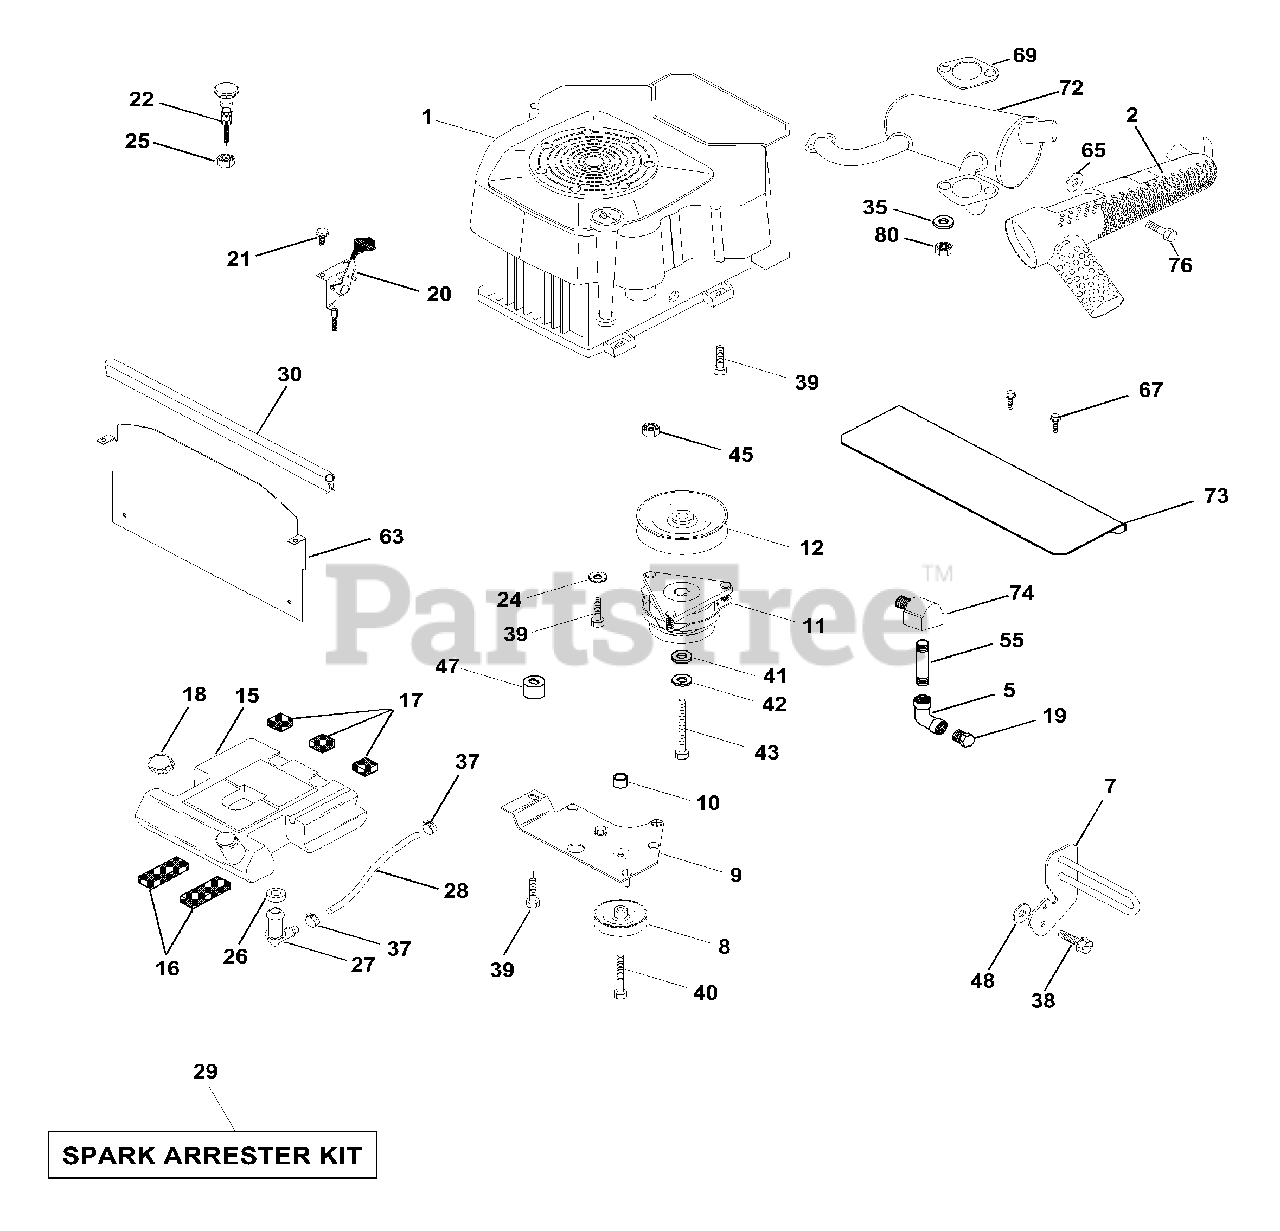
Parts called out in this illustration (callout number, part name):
2	Muffler Side
5	Elbow STD 90 Degree 3/8-18 NPT
7	Muffler Assembly Guard
8	Pulley V-Idler
9	Keeper Asm Belt Engine VGT 96
11	Clutch Electric
12	Pulley Engine VGT Elect Clutch
15	Tank Fuel Rear
16	Pad Spacer
17	Pad Spacer
18	Cap Asm Fuel W/Sym Vented
19	Plug Oil Drain
20	Control Throttle
21	Screw Hex Thd Cut 1/4-20 X 5/8
22	Control Choke
24	Washer Ext Tooth 3/8
25	Nut Keps 3/8 - 24 UNF
26	Bushing
27	Stem Tank Fuel
28	Fuel Line
29	Spark Arrester Kit
30	Extrusion Hood
35	Washer Split
37	Clamp Hose
38	Screw 3/8-16 x 1-1/4
39	Screw TT 3/8-16 x 2-1/4 UNC
40	Screw TT 3/8-16 x 4 UNC
41	Washer 1-1/2 OD X 15/32 ID X .250
42	Washer Lock 7/16
43	Bolt Hex 7/16-20 X 4-1/4 Ga 5
45	Nut Flange M8 1.25
47	Spacer Engine
48	Washer 13/32 x 1-1/4 x 7 Ga.
55	Nipple, Pipe 4-1/2"
63	Shield, Heat VGT YP/Husq.
65	Washer 13/32 x 1 x 14 Ga.
67	Screw 5/16-18 x 3/4
69	Gasket
72	Muffler Pre CV25
73	Shield Heat Muffler
74	Elbow Street Brass
76	Screw 3/8-16 x 3/4
80	Nut Flange M8 1.25
